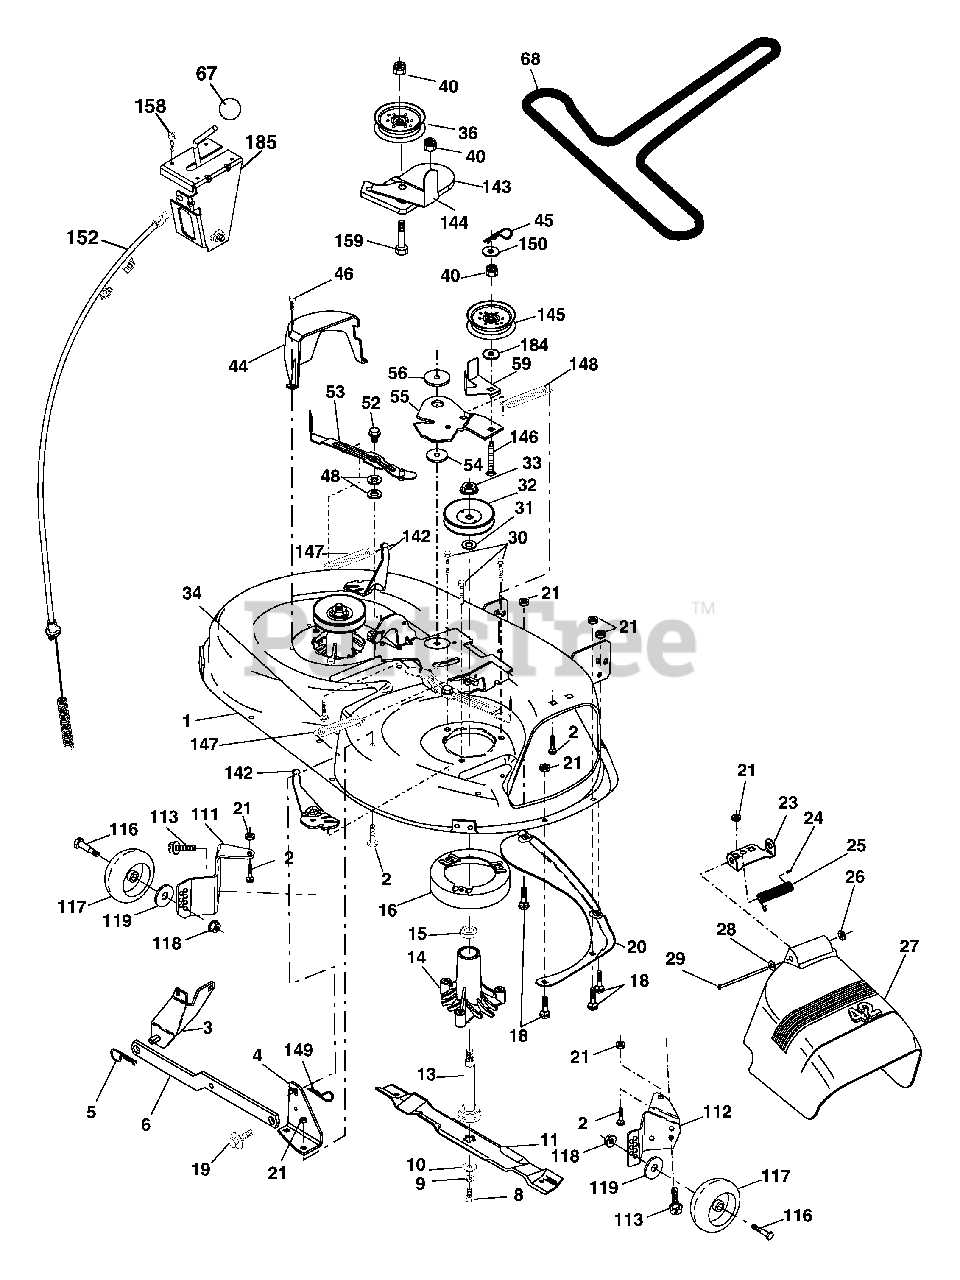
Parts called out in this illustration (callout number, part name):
1	Mower Deck
2	Bolt
3	Bracket Asm Fr. Sway Bar 3/42
4	Bracket Asm Deck 42" Sway Bar
5	Retainer Spring
6	Bar Sway Deck
8	Bolt 3/8-24 x 1.25 Gr. 8 patched
9	Washer, Lock
10	Washer, Hardened
11	Blade Mower 42" Hi-Lift
11	Blade, Mulching 42" Std
11	Blade Mulching 42" Premium
13	Shaft Assembly, Mandrel, Vented
14	Housing, Mandrel, Vented
15	Bearing, Ball, Mandrel
16	Stripper, Mandrel Deck
18	Bolt, Carriage 5/16-18 x 5/8
19	Bolt, Shoulder
20	Baffle, Vortex
21	Nut
23	Bracket, Deflector Mower 42"
24	Cap, Sleeve 80 x 112 Blk Mower
25	Spring, Torsion, Deflector 2 52
26	Nut, Push Phos & Oil
27	Shield, Deflector 42" Blk
28	Washer 11/32 x 5/8 x 16 Ga.
29	Rod, Hinge 42" 6 75 W/G
30	Screw Thdrol
31	Washer, Spacer Mower Vented
32	Pulley, Mandrel
33	Nut, Toplock
34	Bolt Carr SH 3/8-16 x 1-1/2 Gr.5
36	Pulley, Idler, Flat
40	Nut Lock 3/8-16
44	Guard, Mandrel, LH
45	Retainer
46	Screw, Thdrol 1/4-20 x 5/8 T
48	Washer, Hardened
52	Bolt, Shoulder 5/16-18 unc
53	Arm Assembly, Pad, Brake
54	Washer, Hardened
55	Arm, Idler
56	Spacer, Retainer
59	Guard TUV Idler
67	Knob Round
68	V-Belt, 42" Mower
111	Bracket Wheel Gauge LH
112	Bracket Wheel RH
113	Screw 5/16-18 x 3/4
116	Bolt, Shoulder
117	Wheel, Gauge
118	Nut Centerlock 3/8-16
119	Washer 3/8 x 7/8 x 14 Ga.
142	Arm Spring Brake Mower
143	Bracket Arm Idler 42"
144	Keeper Belt 42" Clutch Cable
145	Pulley Idler Flat
146	Bolt Carriage Idler
147	Spring Extension
148	Spring Return Idler
149	Retainer Spring Yellow
150	Washer 9/32 x 3/4 x 10 Ga.
152	Clutch Cable 42"
158	Screw Hex Thd Cut 1/4-20 x 1/2
159	Bolt Rdhd Sqn 3/8-16 unc x 1-3/4
184	Washer 13/32 x 7/8 x 10 Ga.
185	Head Asm Cable Clutch
